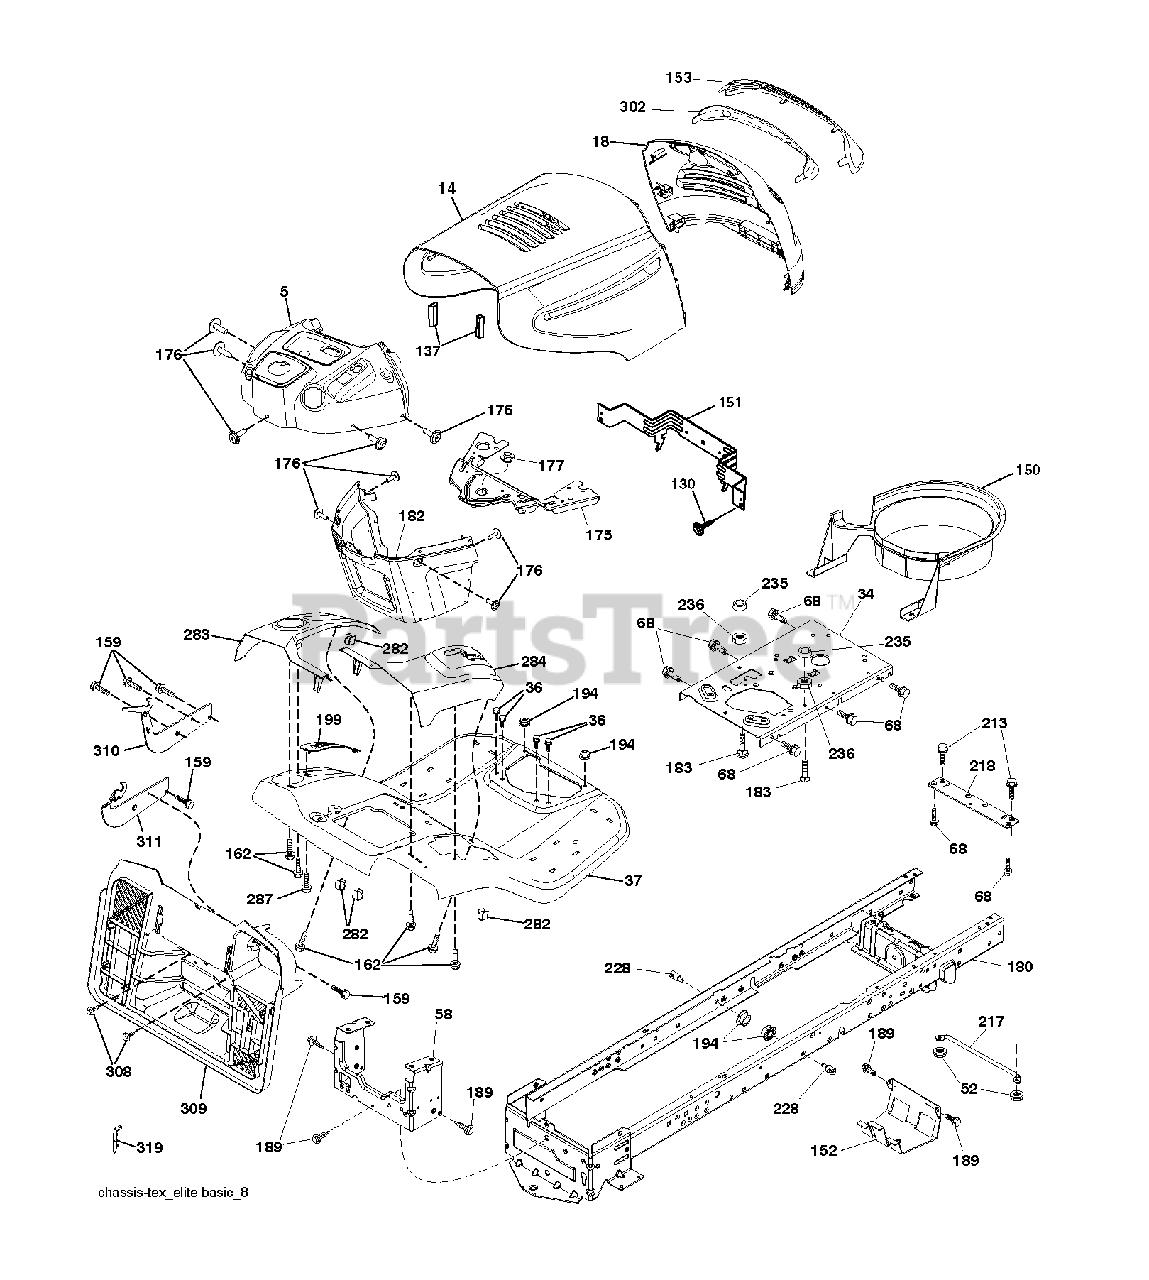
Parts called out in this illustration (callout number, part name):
5	DASH.P/L.TEX.CBL.CL.N/CHK.BLAC
14	GRILLE.BASIC.NO LIGHTS (NLARS)
34	PLATE.ENGINE.WELDED.CHASSIS
36	SCREW 5/16"
37	FENDER.TEX.SRD.CRD.BASE
52	LOCKNUT
58	DRAWBAR UPPER 2PC SMALL FENDER
130	SCREW.#10 X 0.750.BOS THREAD
137	BUMPER.HOOD.LARGE.1.75"
150	DUCT.INTAKE.AIR.KAW
151	BRACKET PIVOT
152	SHIELD BROWNING
153	LENS.GRILLE.BASIC.BAR.LT.CLR
159	SCREW, 3/8-16X3/4
162	SCREW.HI-LO.CONSOLE
175	CROSSMEMBER.LT
176	SCREW.#10-24X5/8.RN.QU
177	BUSHING STEERING
180	CHASSIS.WLDMNT.14GA.2PC.18".TI
182	DASH.LOWER.LT.CCS
183	BOLT.5/16-18X1-1/4 FULL THD
189	SCREW
194	NUT LOCK HEX FLANGE 5/16-18
213	BOLT
217	ROD.PIVOT.HOOD
218	X-PIECE.HOOD.STOP.NON/
228	STUD.FASTNER.W/ANTI-ROTATE
235	SPACER FENDER
236	NUT.CENTERLOCK.5/16-
282	CLIP.RETAINER.CONSOLE.LT.HUSQ
283	CONSOLE.DECKLIFT.LH.SRD.TEXCRD
302	INSERT LENS REFLECTIVE
308	BOLT, 5/16-18 X 1 3/4
309	BACKPLATE.BAGGER.V2.SRD
319	BRACKET.ACTUATOR.BAGGER.SRD
